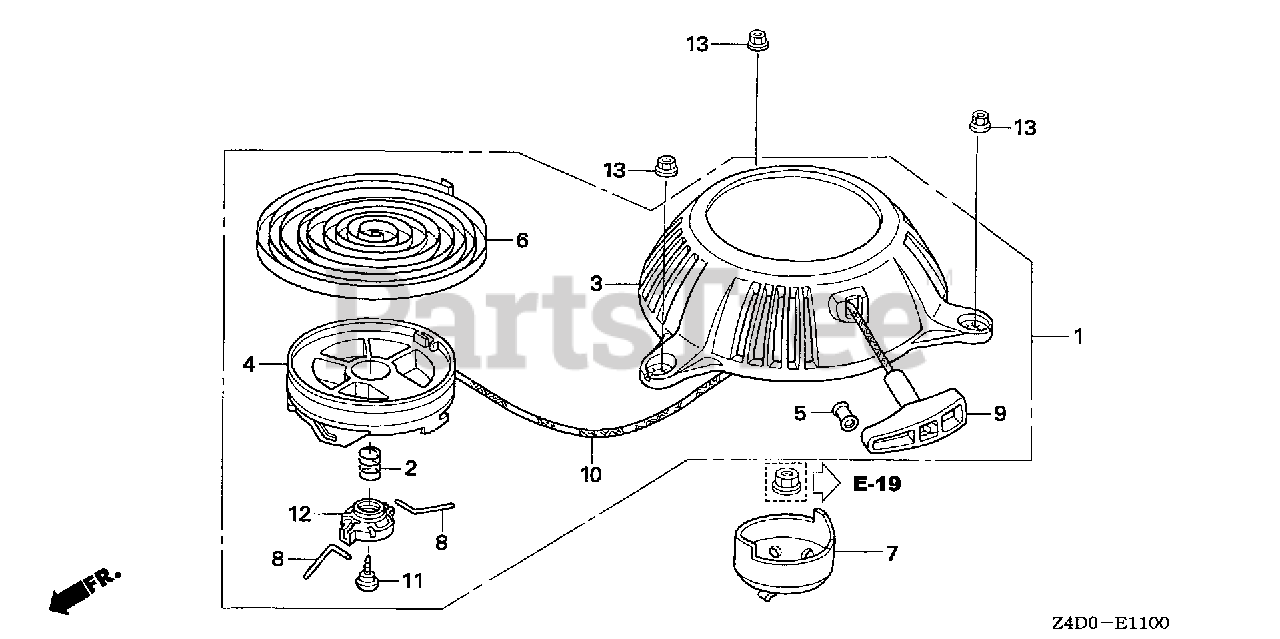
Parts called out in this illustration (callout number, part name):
1	STARTER ASSY., RECOIL
2	SPRING, FRICTION
3	CASE, RECOIL STARTER
4	REEL, RECOIL STARTER
5	GUIDE, ROPE
6	SPRING, RECOIL STARTER
7	PULLEY, RECOIL STARTER
9	KNOB, RECOIL STARTER
10	ROPE, RECOIL STARTER
11	SCREW, SETTING
13	NUT, FLANGE (5MM)
